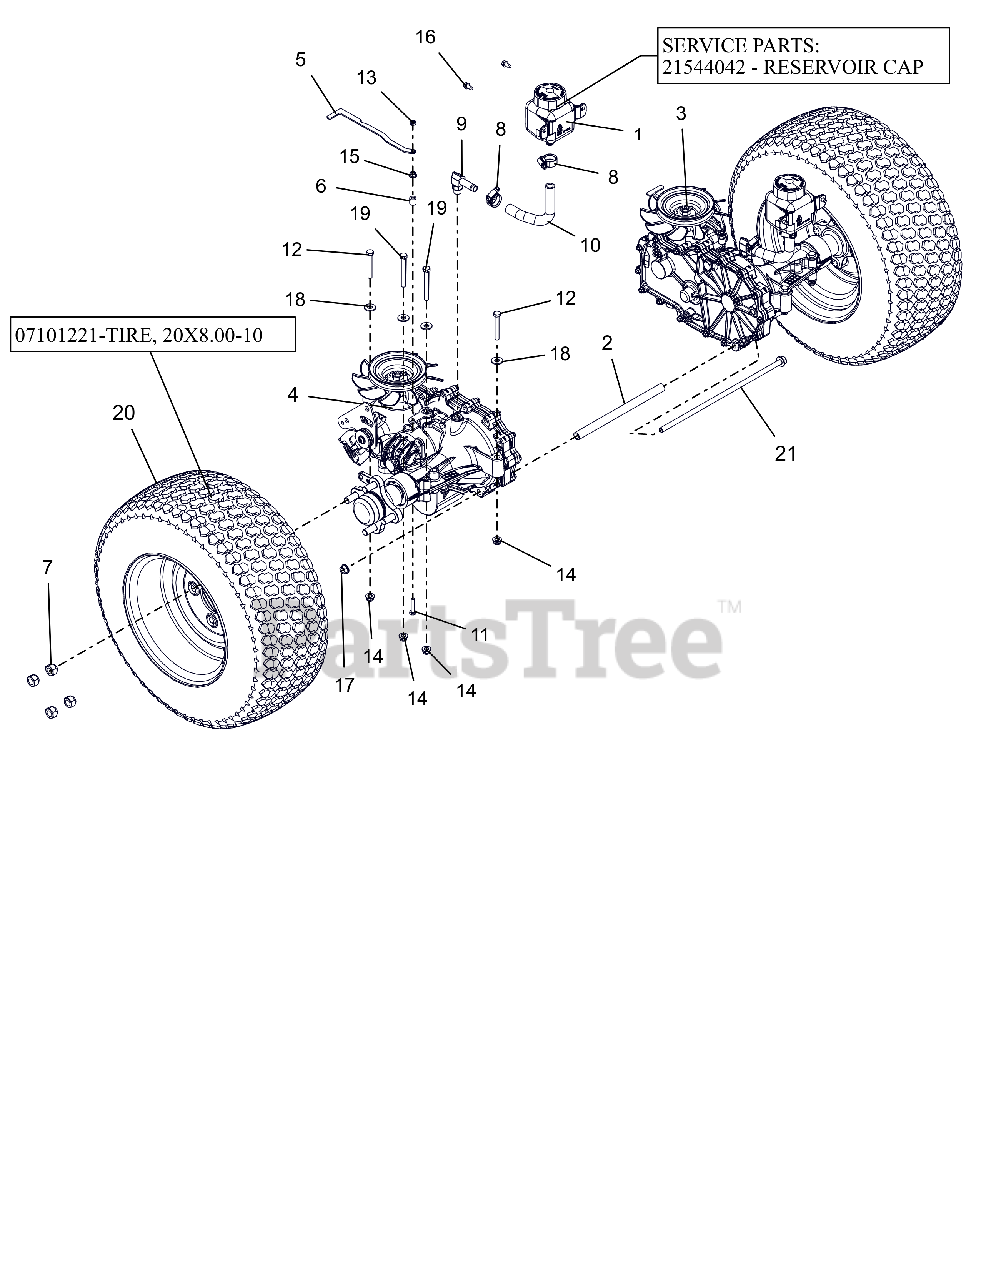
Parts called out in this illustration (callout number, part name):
1	TANK, EXPANSION
1	CAP, HYDRO RESERVOIR REPLAC.
2	TUBE, TRANSAXLE BRACE -9.27LG
3	TRANSAXLE,ZT2800 LH
4	TRANSAXLE,ZT2800 RH
5	BRKT, DUMP VALVE
6	BSHG-SLV .265X.500X.500
7	WHEEL NUT .500-20 YZ
8	CLAMP,.88 DIA. HOSE
9	FITTING, HYD (90 DEG)
10	HOSE, FORMED LH XL
11	@BLT-HEX .25-20X1.25 GR5 YWZC
12	@BLT-HEX .31-18X2.25 GR5 YWZC
13	NUT-LK-CTR JAM .25-20 YWZC
14	@NUT-LK-NYL-FLG .31-18 YWZC
15	@NUT-SPNLK-FLG .25-20 YWZC
16	SCR-TAP .25-20X.50 HWH TR YWZ
17	NUT-LK-CTR-FLG .375-16 GF ZCC
18	@WSHR-FL-STL.38X.875X.083 YWZC
19	@BLT-HEX .31-18X2.75 GR5 YWZC
20	ASM, WHL/TIRE 20X8.00-10
20	TIRE, 20X8.00-10
20	TUBE, 20X10-10
21	BLT,HEX-FLG .38-16X13 G5 ZCC
